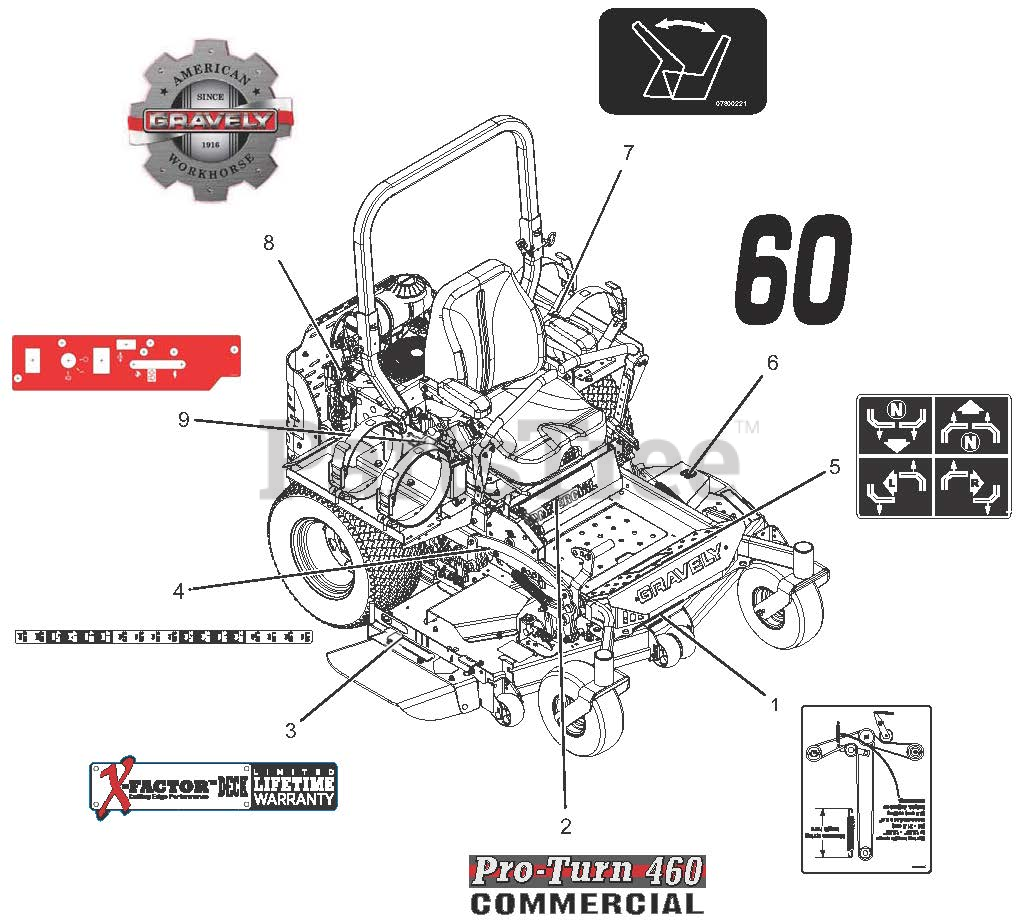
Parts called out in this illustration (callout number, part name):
1	DECAL, BELT DIAGRAM
2	DECAL, PT460
3	DECAL, X-FACTOR DECK
4	DECAL, PT400 HEIGHT OF CUT
5	DECAL, INSTRUCTIONAL -STEERING
6	DECAL, 60"
7	DECAL, SEAT RELEASE
8	DECAL, GRAVELY HERITAGE - LARG
9	DECAL, CONTROL PT400-LP
